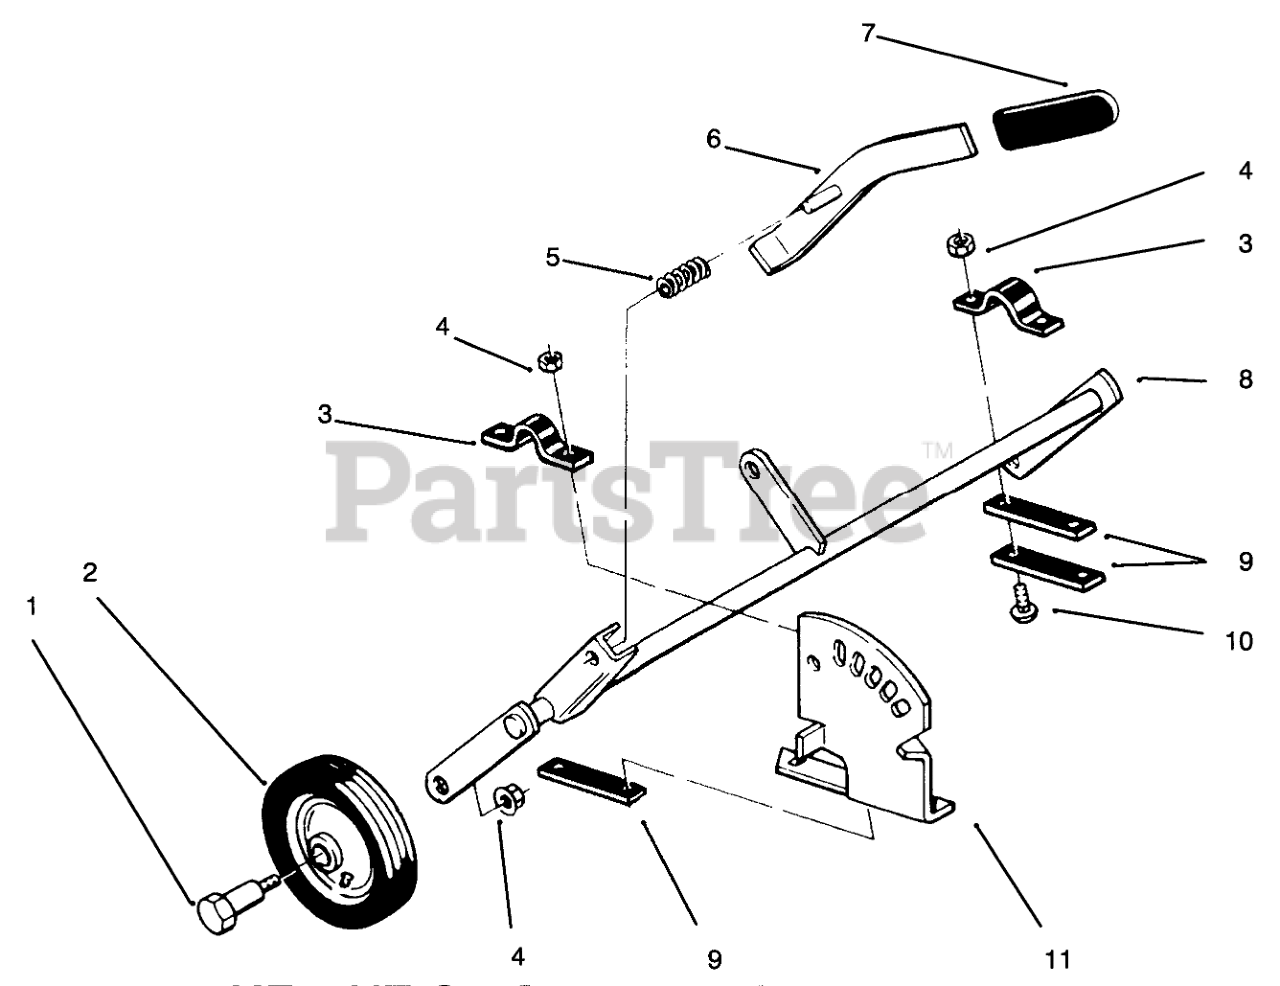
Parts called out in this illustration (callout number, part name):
1	BOLT-SHOULDER
2	WHEEL
4	NUT-HEX
5	SPRING-COMPRESSION
6	Lever
8	Gage Wheel Support
9	Bar
10	BOLT-CARR
11	Quadrant
